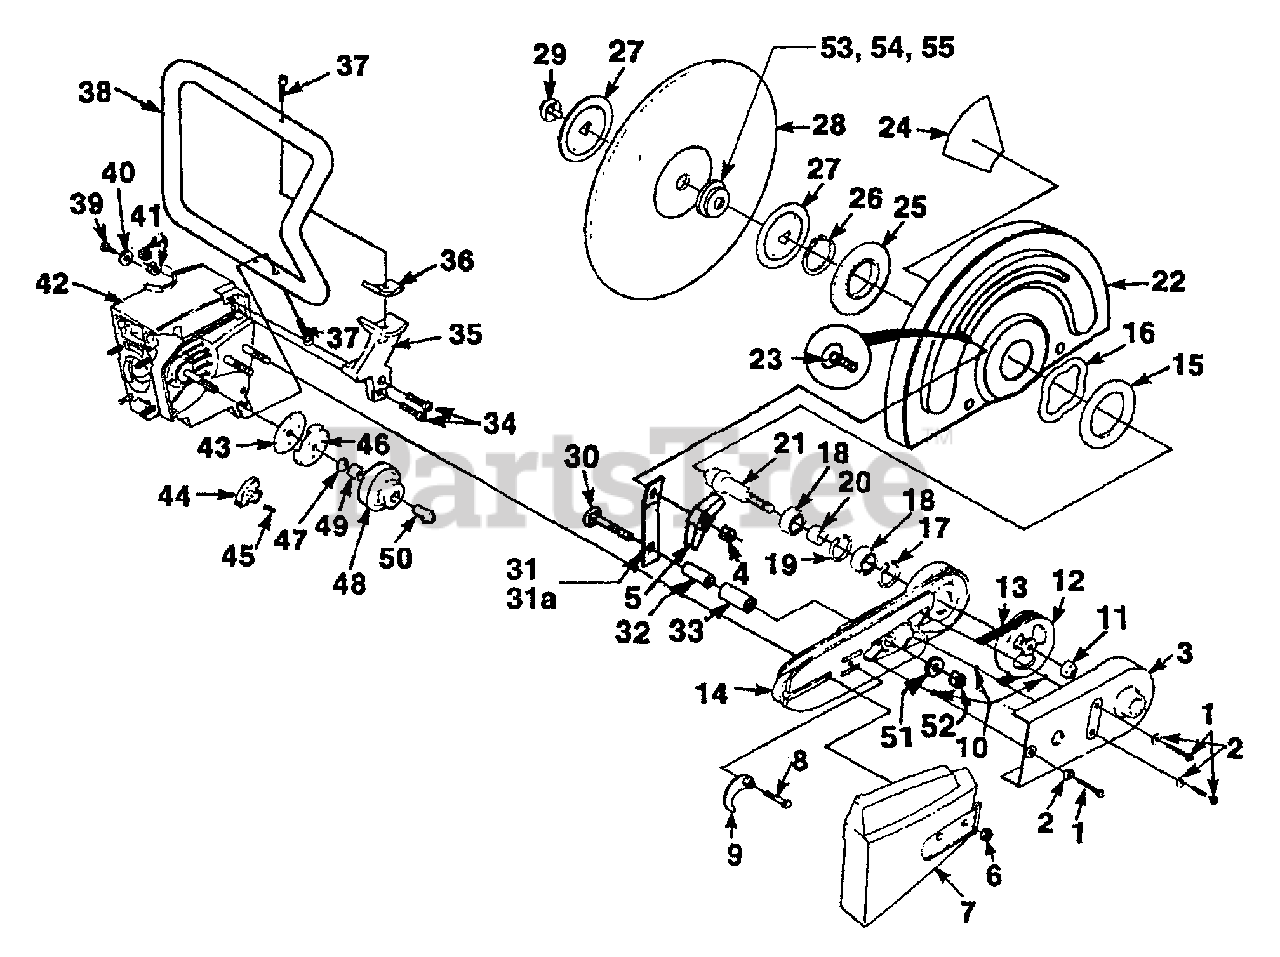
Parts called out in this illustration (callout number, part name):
1	SCREW-Slotted (1/4-20 X 1 1/2")
2	WASHER-Flat
3	COVER-Arm
4	NUT-Hex (5/16-18)
5	KNOB-Handle
6	NUT-Hex (10-24)
7	COVER-Drivecase
8	SCREW-Hex hd. (5/16-18 X 1 1/2")
9	CAM & ADJUSTER
10	"O" RING
11	NUT-Hex (1/2-13)
12	PULLEY-Drive
13	BELT-"V" Drive
14	ARM-Wheel
16	SPRING-Wave
17	RING-Retaining
18	BEARING-Ball
19	RING-Retaining
20	SPACER-Bearing
21	SHAFT-Wheel
22	WHEEL GUARD KIT (12")
23	BOLT-Step (5/16-18 X 3/4")
24	LABEL-Caution
25	WASHER-Mounting
26	RING-Retaining
27	FLANGE-Wheel
28	WHEEL-Resinoid (12")
28	WHEEL-Resinoid (14")
29	KIT-Screw, Washer, Ret. Ring
30	BOLT-Step (3 1/2")
31	ARM-Adjusting (12")
31A	ARM-Adjusting (14")
32	SKIRT-Rubber
33	TUBING-Rubber
34	SCREW-Hex hd. (12-24 X 7/8")
35	BRACKET-Handle bar
36	MOUNT-Shock (bracket)
37	SCREW-Nylock (1/4-20 X 1")
38	HANDLE BAR
39	SCREW-Pan hd.
41	NUT-Hex (12-24)
42	CRANKCASE
43	COVER-Clutch
44	CLUTCH ASSEMBLY
45	SPRING-Clutch
46	PLATE-Clutch
47	WASHER-Thrust (Inner)
48	PULLEY-Bearing & Arm
49	BEARING-Needle
50	INNER RACE KIT
51	WASHER-Flat
52	NUT-Hex (5/16-18)
53	SPACER-1" Dia.
54	SPACER-22mm Dia.
55	SPACER-20mm Dia.
